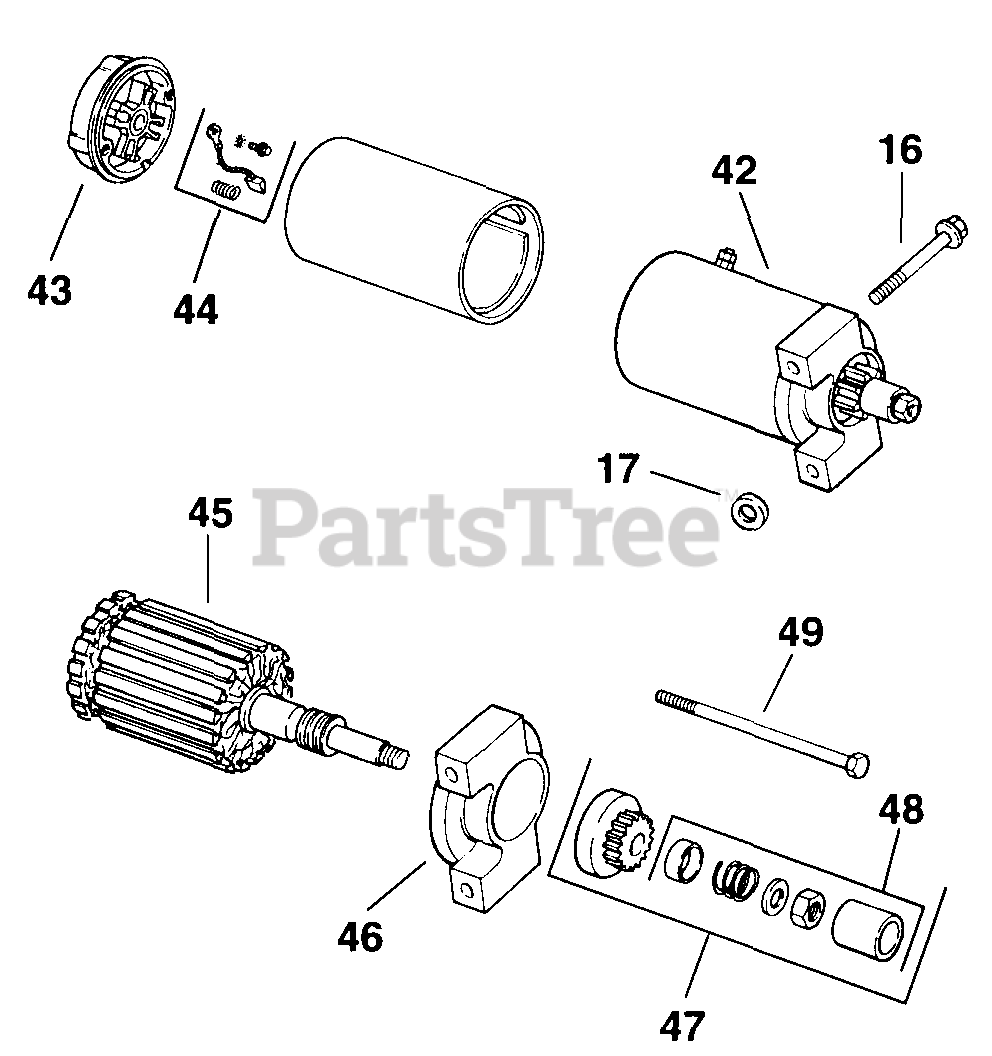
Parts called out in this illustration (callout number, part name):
17	WASHER, FLAT 11/32"
42	STARTER - USE 12 098 12
44	KIT - USE 82 755 28
45	ARMATURE - DISCONTINUED
46	CAP - USE 12 227 05
47	DRIVE KIT - USE 12 755 53
48	DRIVE KIT - USE 12 755 53
49	SCREW - DISCONTINUED
